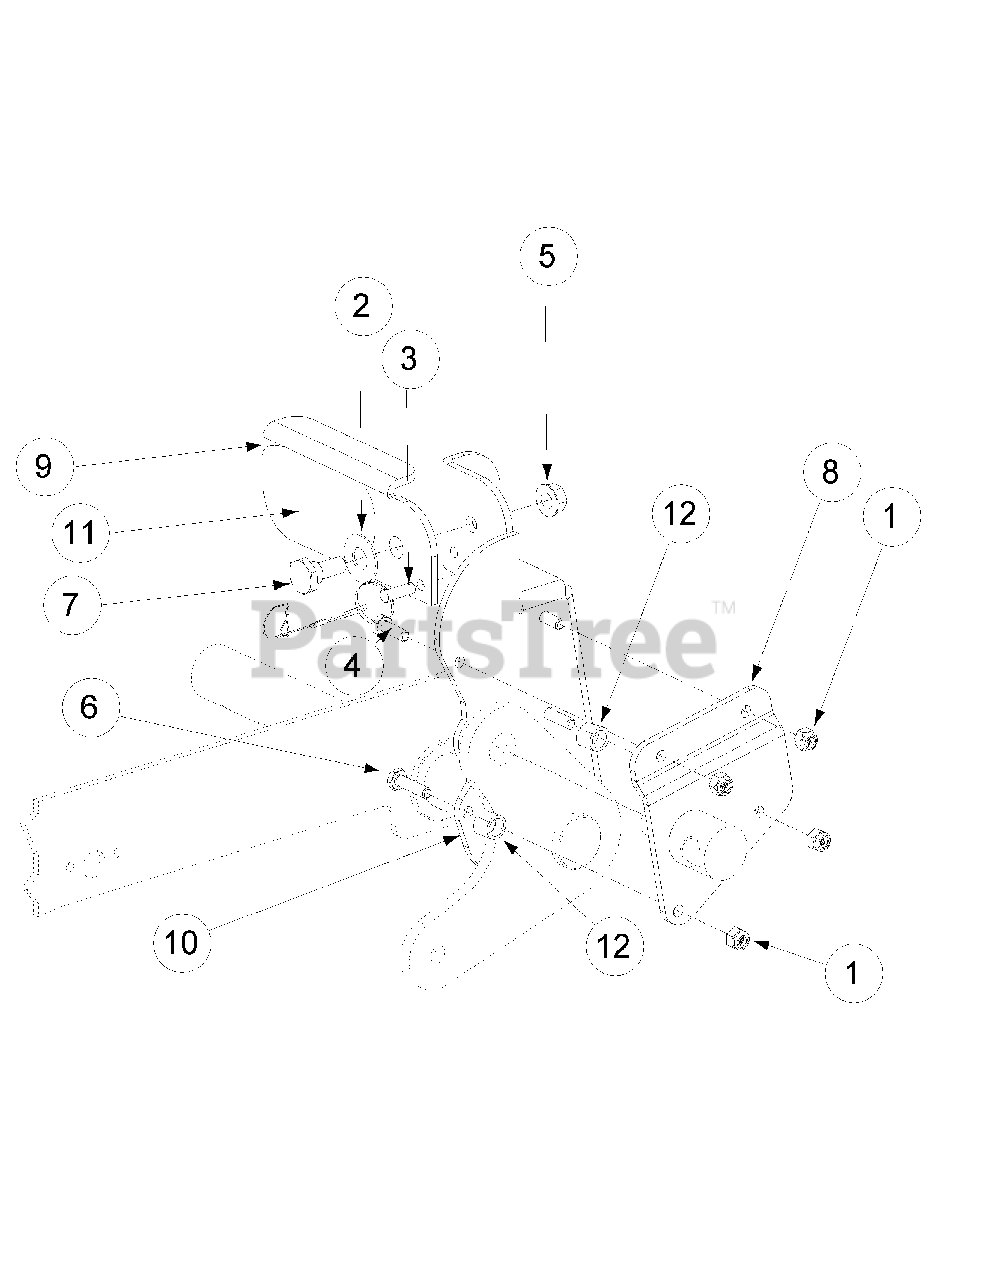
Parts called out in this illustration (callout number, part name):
1	Lock Nut, Nylon Insert, 1/4-20
2	Washer, 1/2 x 1 Shim
3	Detent Pin w/12" Lanyard
4	Hex Cap Screw, 1/4-20, .75
5	Hex Nut, Flange Lock 3/8-16
6	Hex Cap Screw, 1/4-20, 1.00
7	Shoulder Screw, .50 x .27 Lg., 3/8-16
8	Foot Lift Backup Pedal
9	Deck Lift Foot Pedal
10	Deck Lift Foot Pedal
11	Deck Lift Foot Pad
12	Turnbuckle Sleeve
